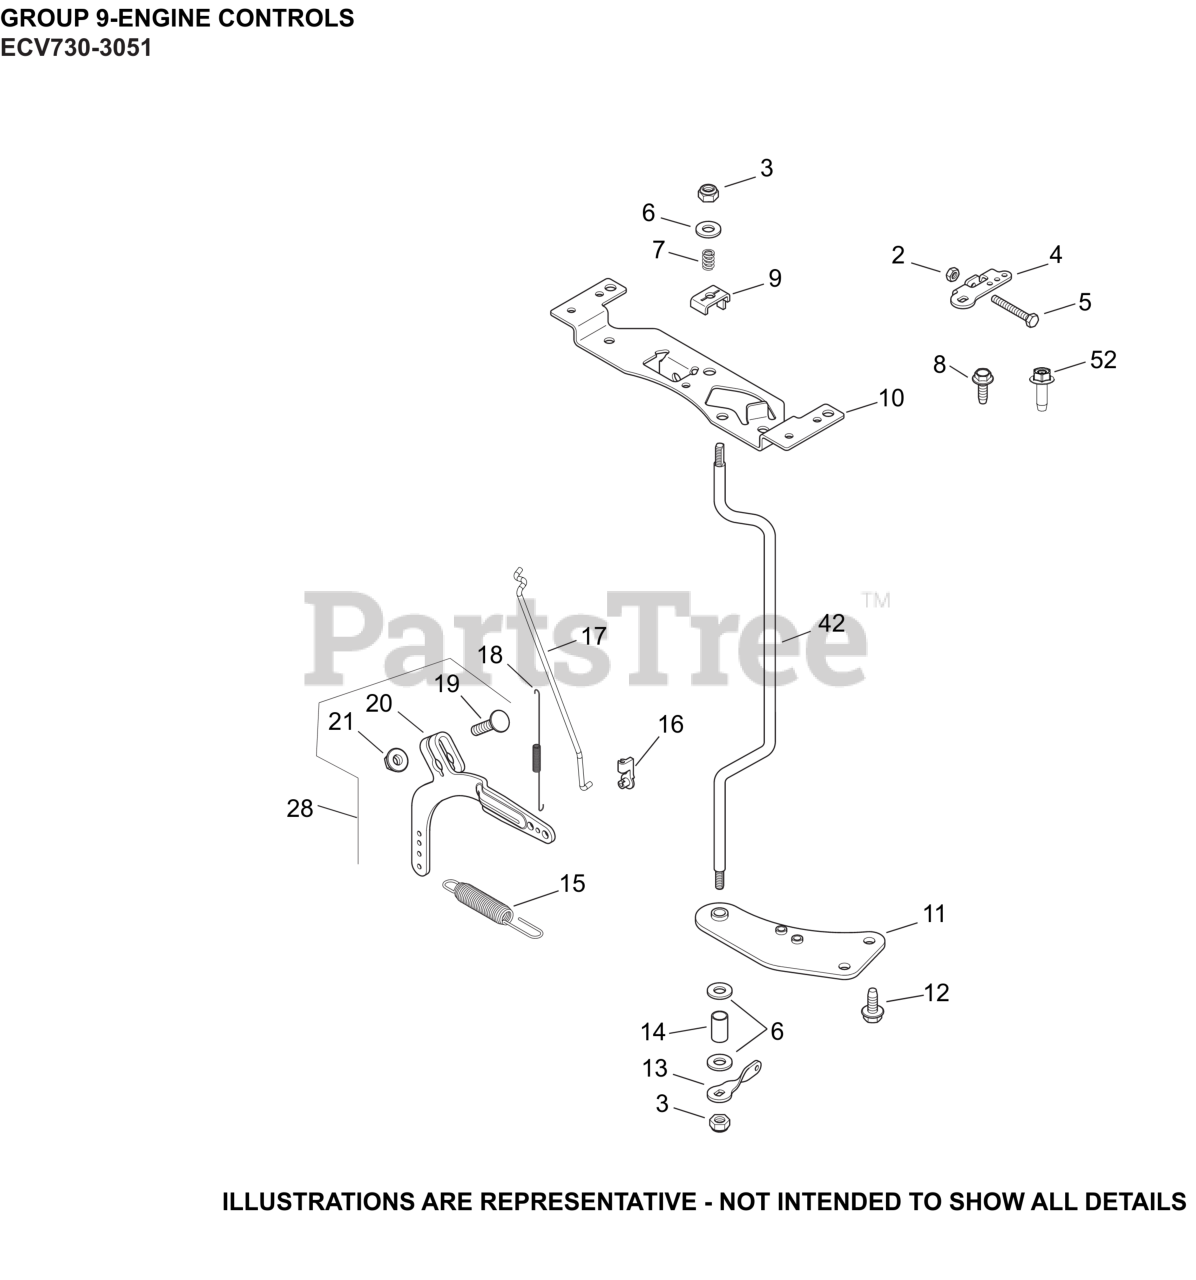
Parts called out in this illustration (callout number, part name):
2	NUT, M4X0.7
3	NUT, LOCK M6X1.0
4	LEVER, THROTTLE CONTROL
5	SCREW, CAP M4X.7X30
6	WASHER, FLAT 1/4"
7	SPRING, THROTTLE SHAFT
8	SCREW, MATHREAD M5 X 0.8 X 16
9	CLAMP, CABLE
10	BRACKET, CONTROL
11	BRACKET, THROTTLE SHAFT
12	SCREW, THREAD FORMING
13	LEVER, THROTTLE CONTROL
15	SPRING, GOVERNOR (BLUE)
16	BUSHING, THROTTLE LINKAGE
17	LINKAGE, THROTTLE
18	SPRING, LINKAGE
19	BOLT, RD HD SQ NECK M6X1.0X25
20	LEVER, GOVERNOR - (#2409069S)
21	NUT, FLG M6X1.0
28	LEVER, GOVERNOR ASSEMBLY
42	THROTTLE CONTROL SHAFT
52	SCREW, THREAD FORMING
